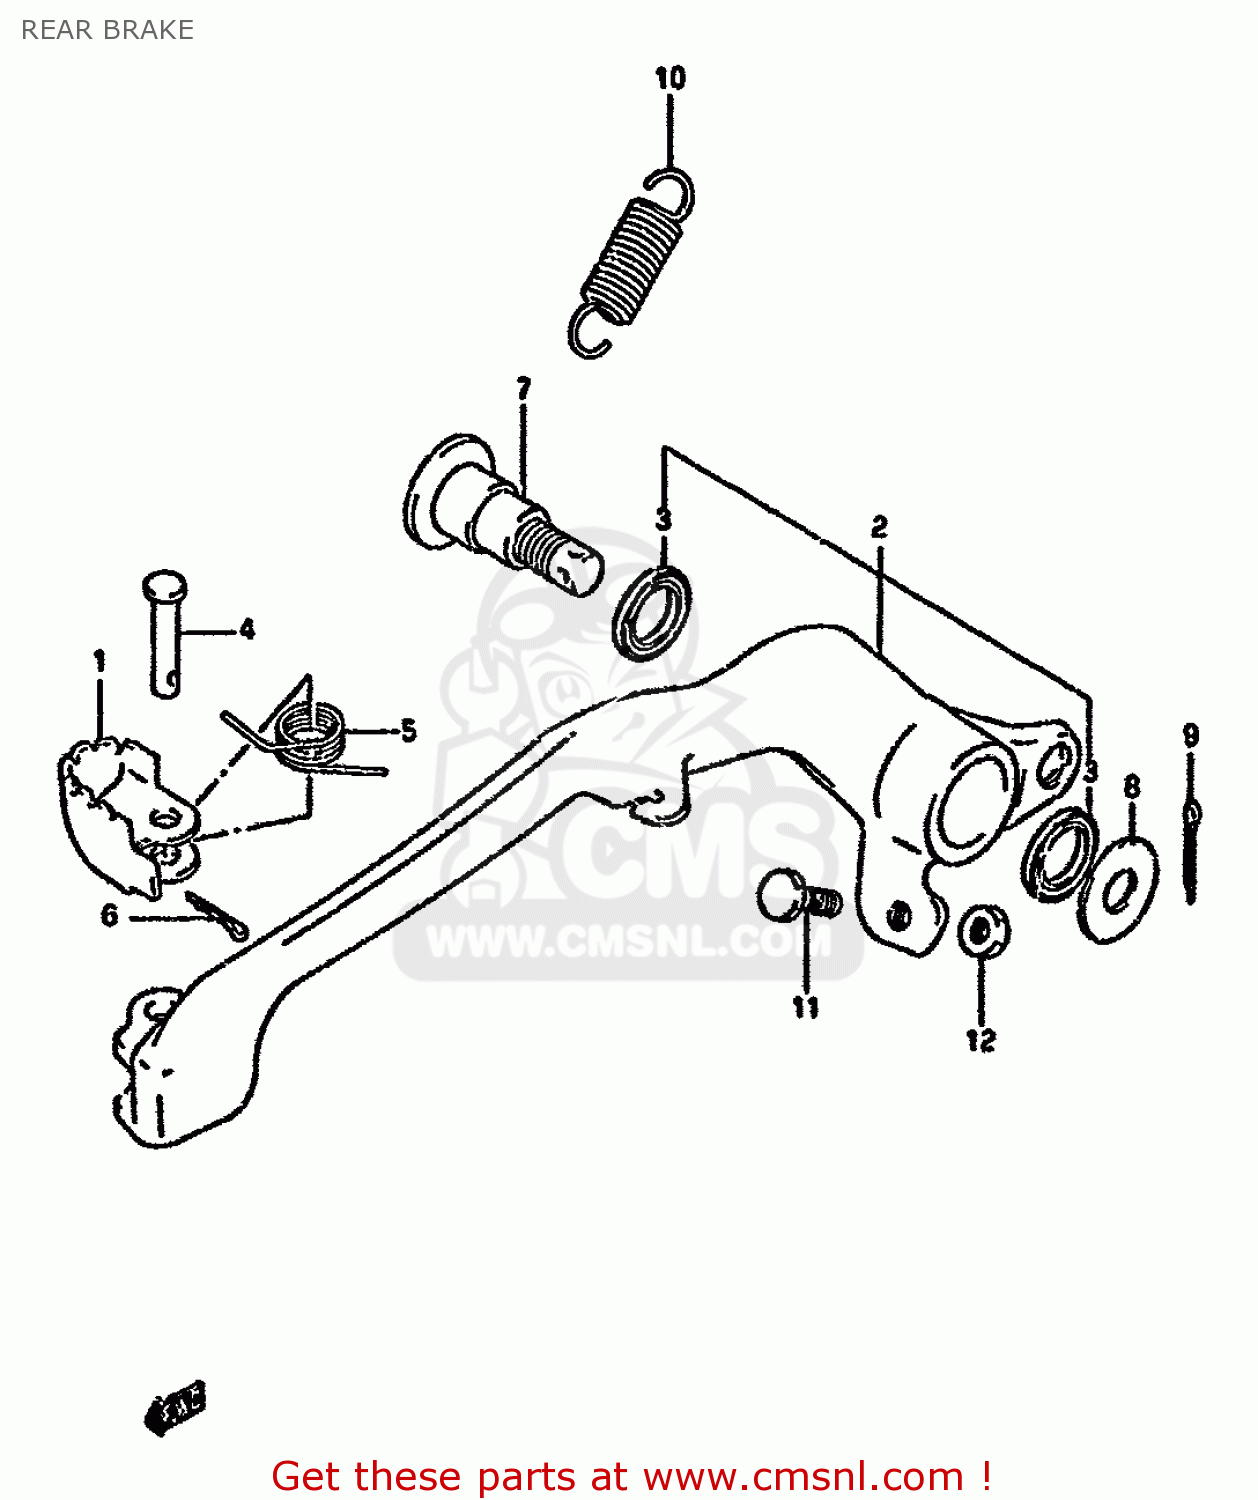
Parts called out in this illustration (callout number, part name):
1	PEDAL,BRAKE
2	ARM,BRAKE PEDAL
3	SEAL,OIL(15X21X3)
4	PIN(6X23.5)
5	SPRING
6	PIN
7	SHAFT,BRAKE PEDAL
8	WASHER
9	PIN 20X20
10	SPRING
11	BOLT(6X23)
12	NUT
